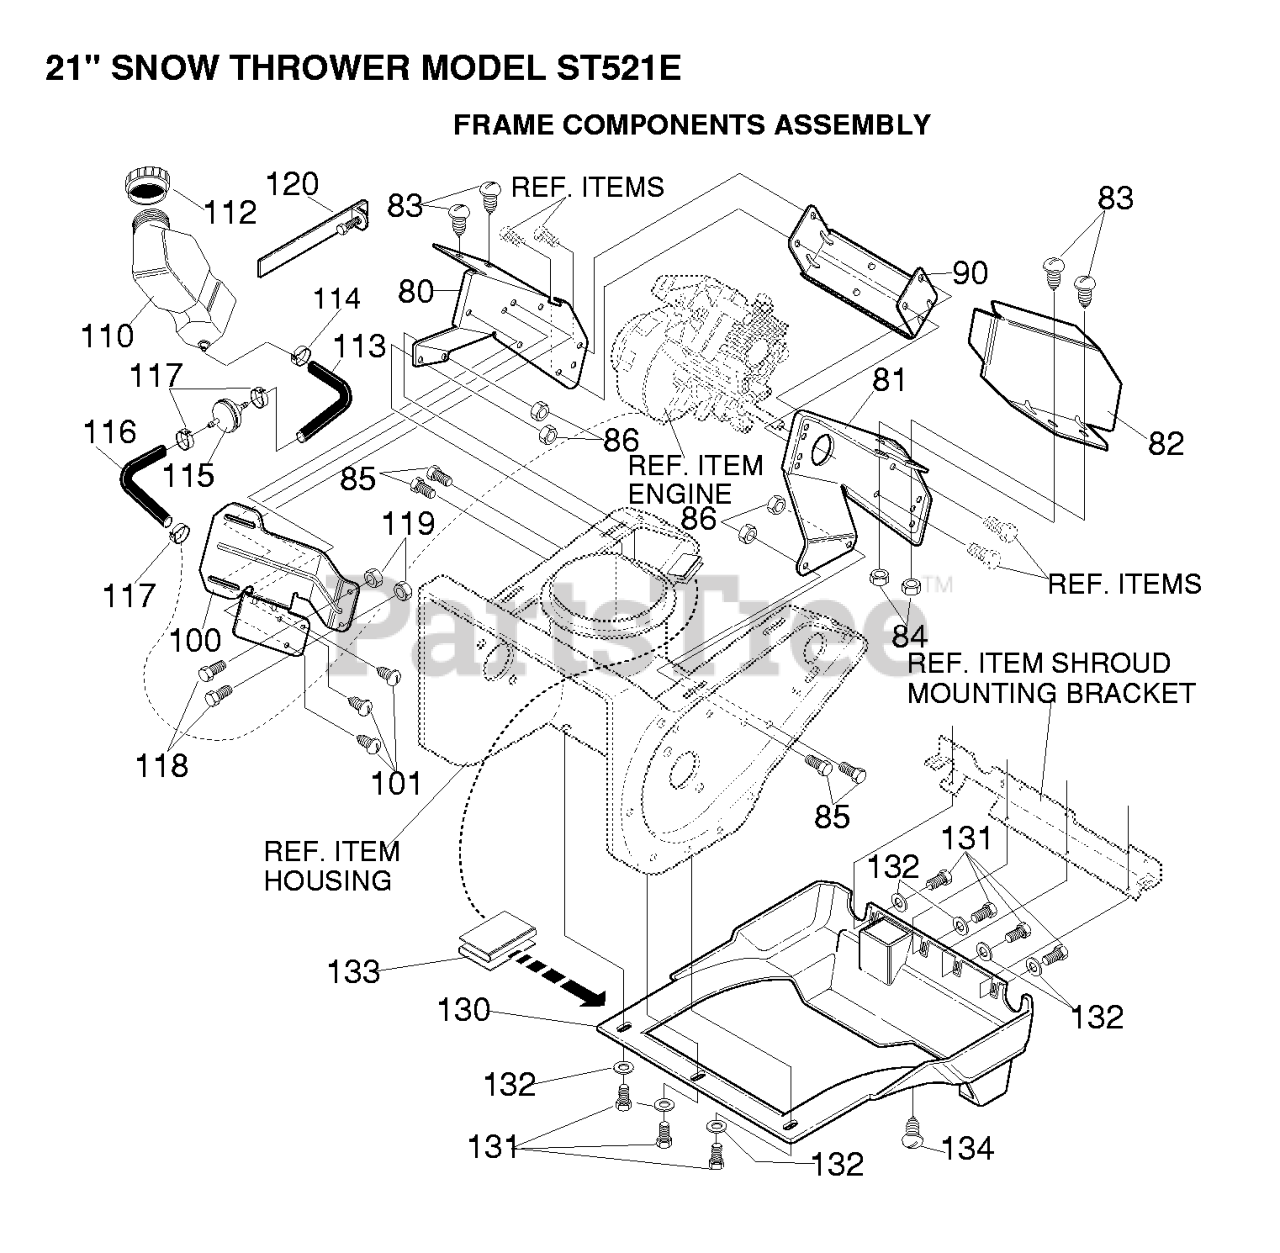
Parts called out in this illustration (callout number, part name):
80	PLATE, REAR MT RH
81	PLATE, REAR MT LH
82	SHIELD, ENGINE HEAT
83	SCREW, 1/4-20X.63
84	NUT 1/4-20
85	SCREW 5/16-18X.50
86	NUT, 5/16-18 REGHEXCTRLK
90	SUPPORT, FRAME
100	BRACKET, GAS TANK 2 CY
101	SCREW, #10-24X.63
110	TANK, FUEL, 1.62 QT.
112	CAP, FUEL, W/2654 SEAL
113	TUBING, GAS LINE 8 IN.
114	CLAMP, HOSE
115	FILTER, IN-LINE
116	TUBING, GAS LINE 3 IN.
117	CLAMP, TUBING
120	CLAMP, WORM DR
130	SHROUD, BOTTOM
131	SCREW, #10-24X.63
133	CLIP, "S" TINNERMAN
134	SCREW, 10-16X.50 DRILLITE
